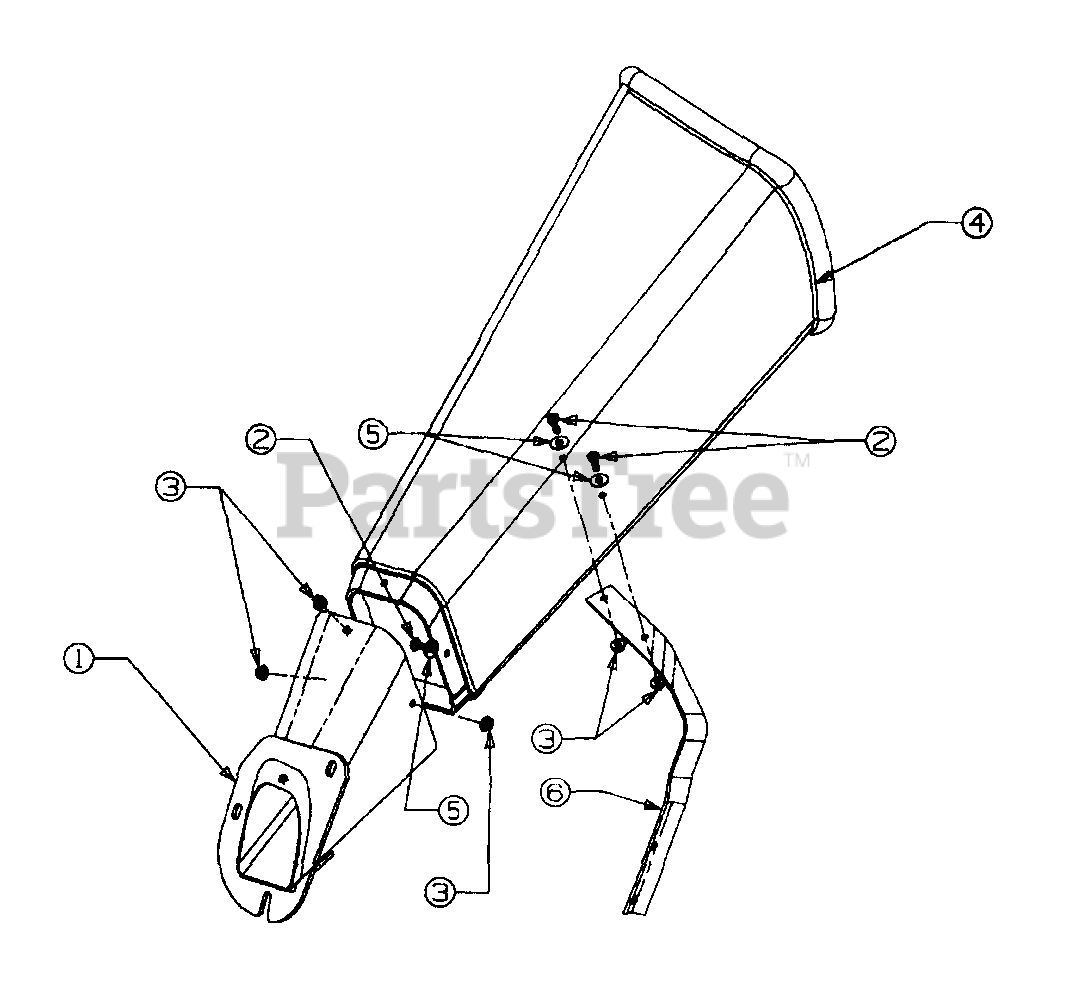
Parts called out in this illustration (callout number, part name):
3	NUT-LOCK
4	CHUTE-UPPER
6	WASHER
